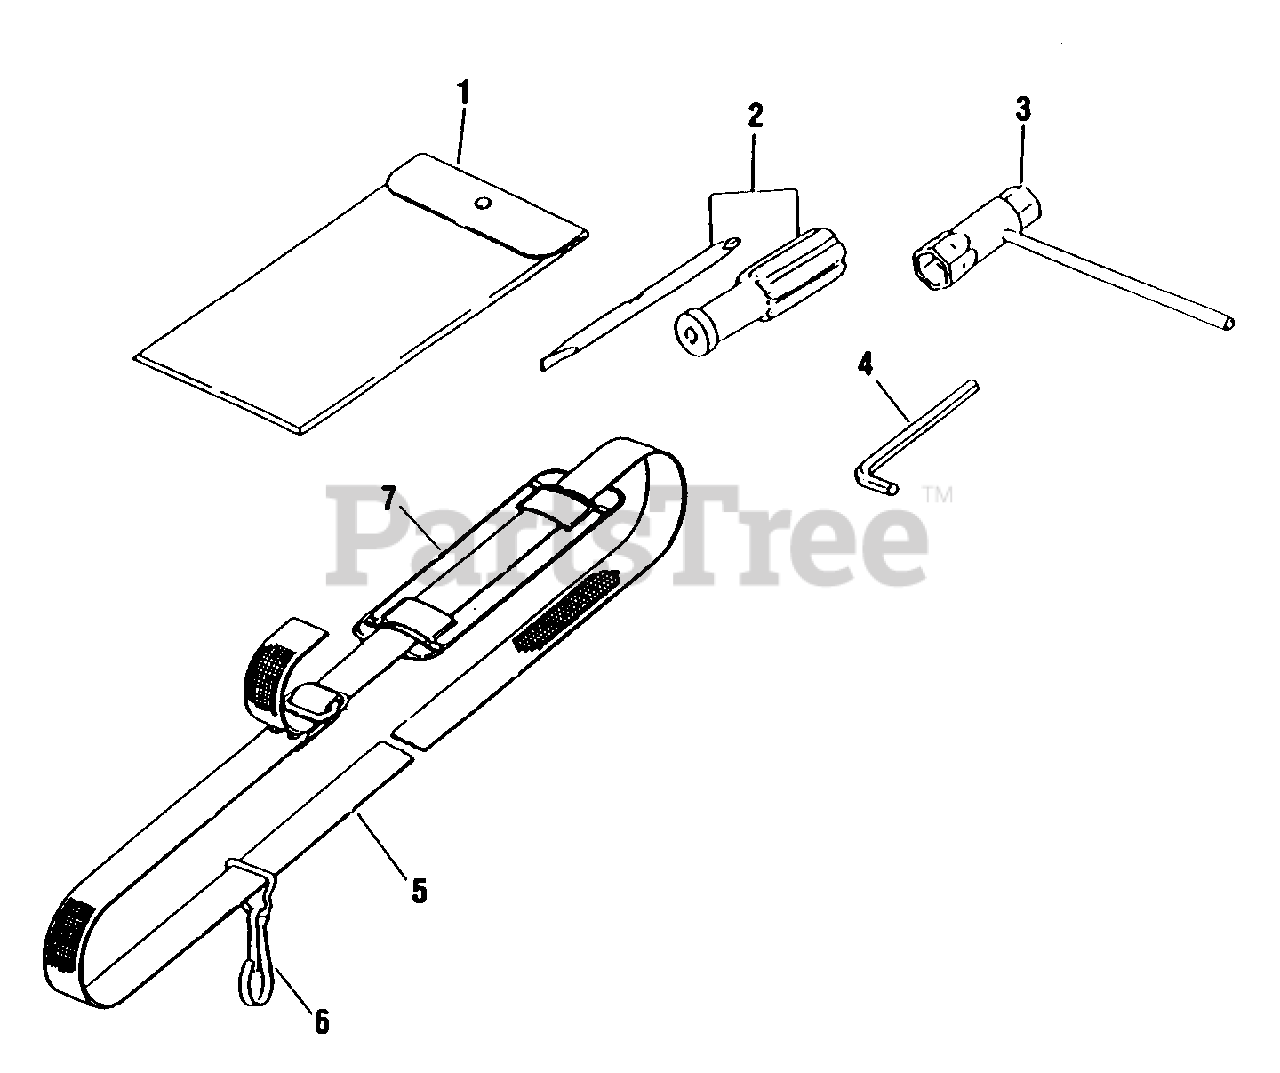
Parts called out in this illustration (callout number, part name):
1	BAG, TOOL
2	SCREWDRIVER
3	T-WRENCH - 13X19mm
4	HEX KEY - 4mm
5	BELT
7	PROTECTOR
